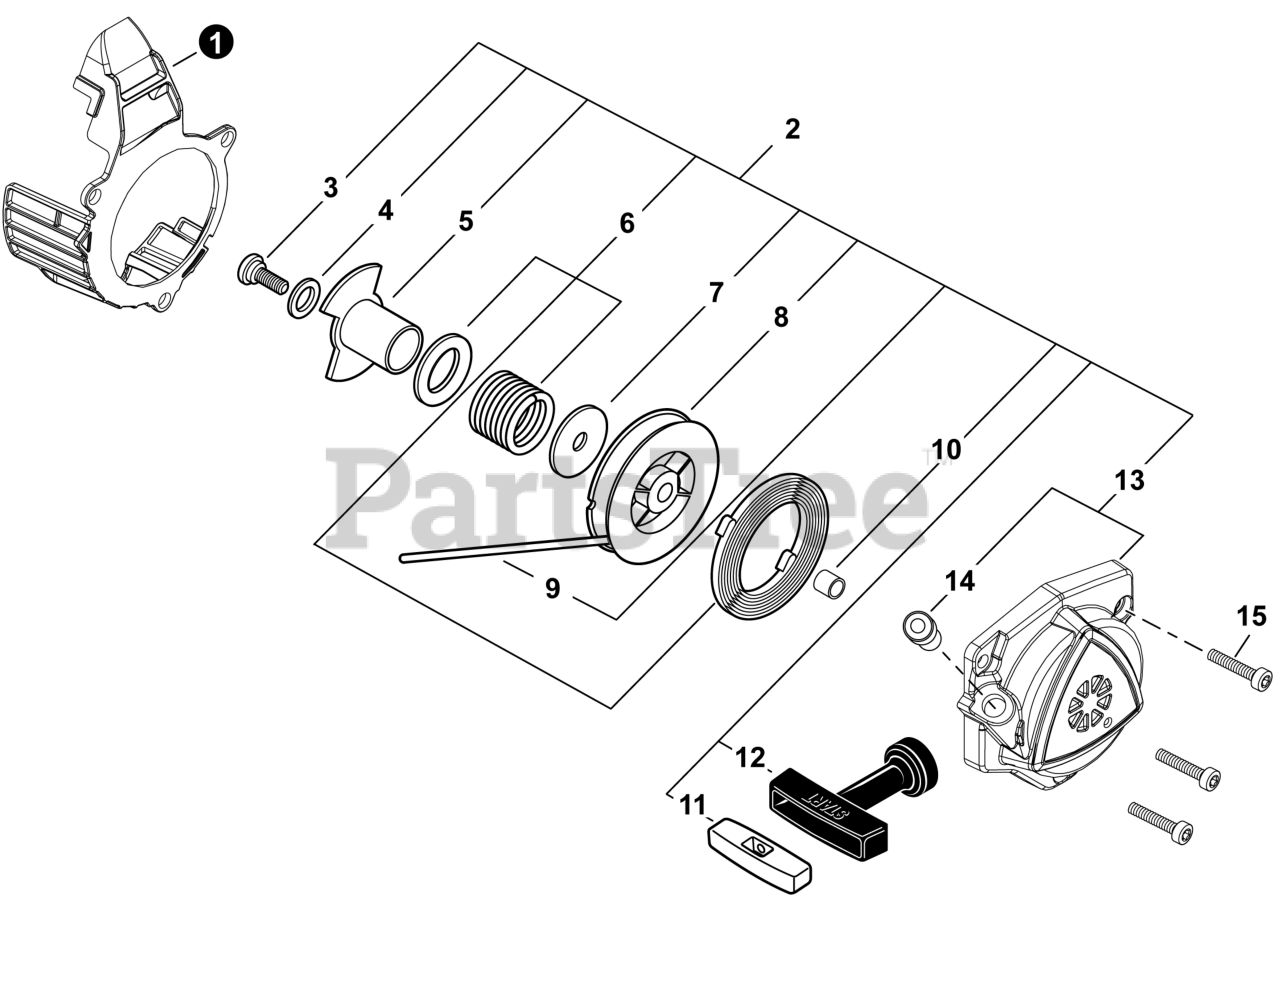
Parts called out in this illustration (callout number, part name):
1	GUARD, DEBRIS
2	STARTER ASSY, RECOIL
3	SCREW 5
4	WASHER, THRUST
5	PLATE, FRICTION
6	KIT, SPRING
7	WASHER 20.7
8	REEL, ROPE
9	ROPE, STARTER
10	COLLAR
11	RETAINER, ROPE
12	GRIP, STARTER
13	CASE, STARTER
14	GUIDE, ROPE
15	BOLT 5x20
